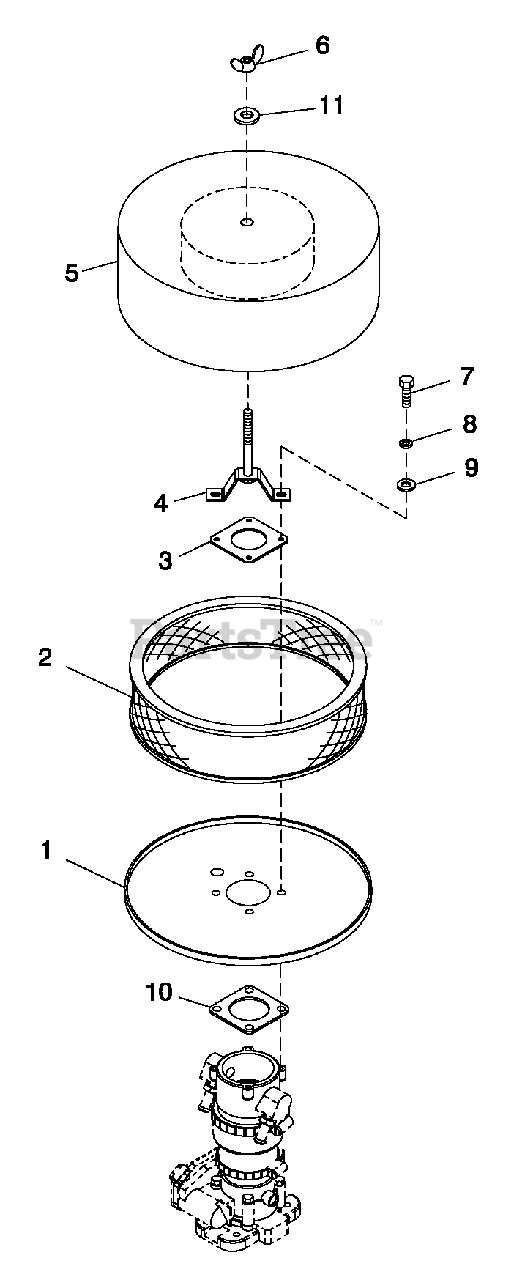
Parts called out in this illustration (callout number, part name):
1	AIR CLNR BTM PLT W/CPLR 8.1L
2	ELEMENT AIR FILTER
3	TOP PLATE VENTURI
4	HOLD DOWN AIR CLEANER PLATED
5	PLATE AIR CLEAN TOP 5.4L/6.8L
6	NUT WING 1/4-20 NYLK
7	SCREW HHC M6-1.0 X 16 G8.8
8	WASHER LOCK M6-1/4
9	WASHER FLAT M6
10	GASKET MIXER BODY
11	WASHER FLAT 1/4-M6 ZINC
